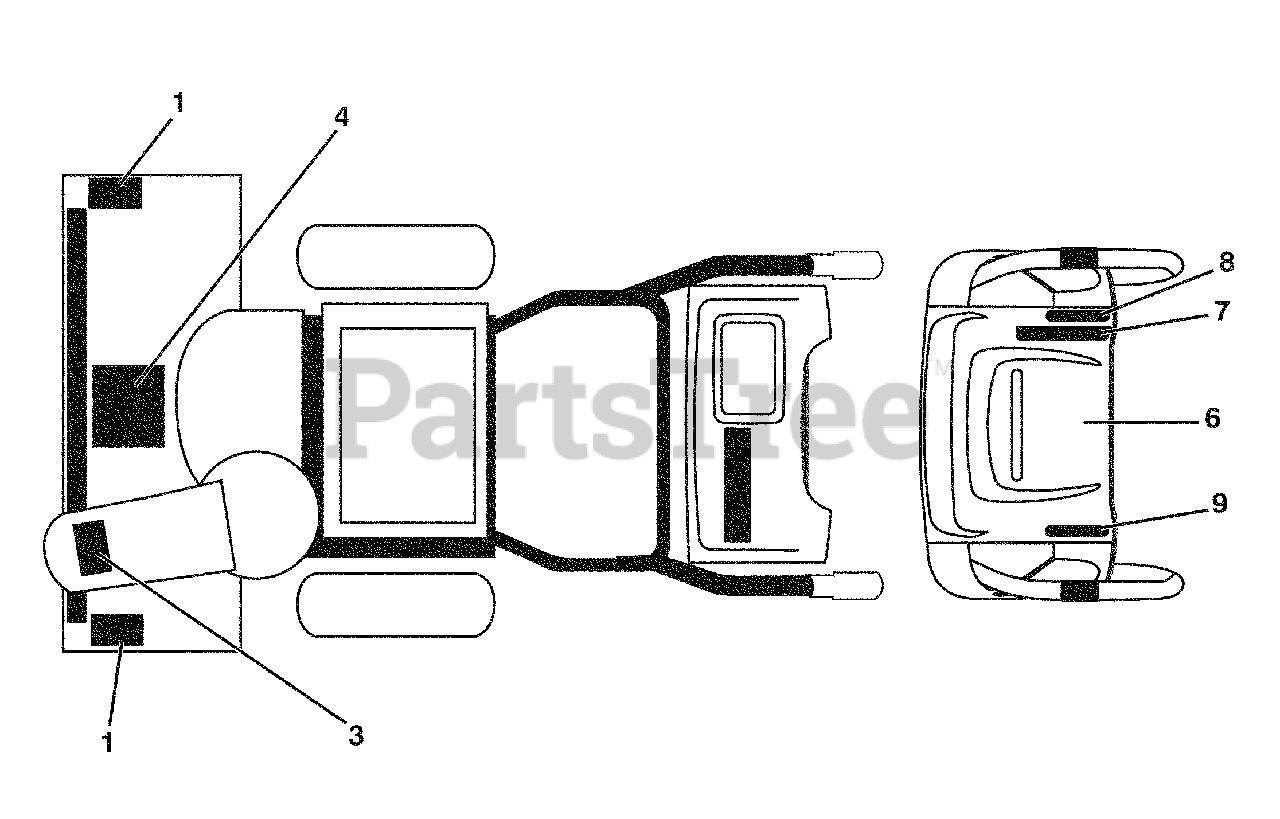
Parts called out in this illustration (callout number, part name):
1	DECAL, DANGER
3	DECAL, DANGER, DEFLECTOR
4	DECAL, DANGER
6	DECAL, INSTRUCTION, E/F
7	DECAL, SPEED CONTROL
8	DECAL, AUGER, LEVER
9	DECAL, TRACT/CLUTCH. LEV. LH
